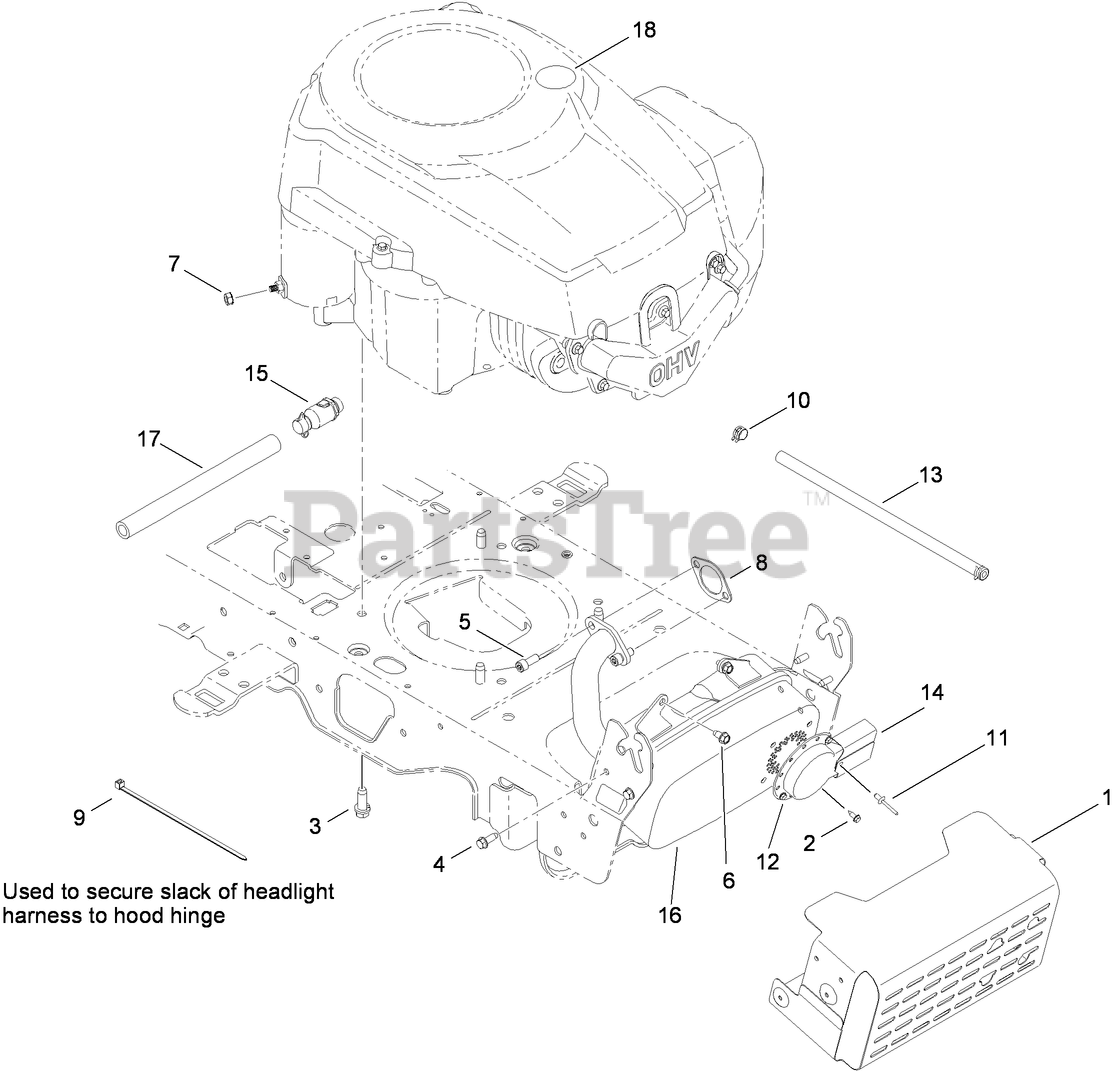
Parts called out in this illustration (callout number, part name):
1	SHIELD-MUFFLER
2	SCREW-HWHTF
3	SCREW-HH, TAP
4	SCREW-HWHTF
5	SCREW-HSH
6	SCREW-HWH
7	NUT-SEMS
8	GASKET-EXHAUST
9	TIE-CABLE
10	CLAMP-HOSE
11	RIVET-POP
12	DEFLECTOR-MUFFLER
13	HOSE-FUEL
14	DEFLECTOR-MUFFLER, LONG
15	DRAIN-OIL
16	MUFFLER
17	HOSE-DRAIN
18	DECAL-CHECK OIL
